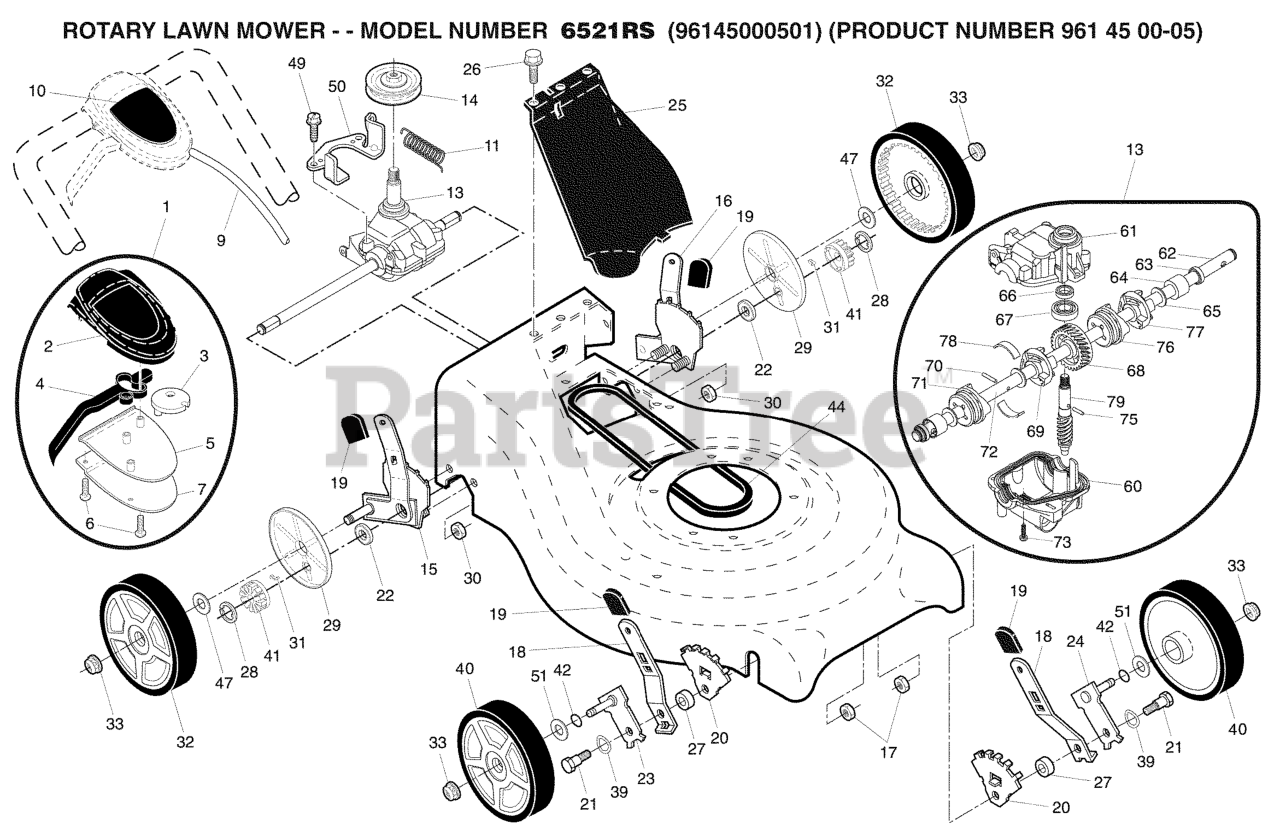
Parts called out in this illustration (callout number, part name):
1	DRIVE CONTROL ASSY, AUTO WALK
2	COVER.TOP.DRIVE.CONTROL.BLACK
3	PULLEY.CAM.DRIVE.CONTROL.EZ
4	LEVER, AUTOWALK DRIVE CONTROL
5	COVER.BOTTOM.DRIVE.CNTRL.BLACK
6	SCREW, PHILLIPS HEAD 10 X 5/8
7	BRACKET.DRIVE.CONTROL.MOUNT.BL
9	CABLE.ASSY.RGD.EZ.AUTO
10	DECAL, DRIVE
13	TRANSMISSION.21.RWGD
14	PULLEY.1.PIECE
15	KIT.ADJUSTER.ASM
16	KIT WHEEL ADJ LH
17	LOCKNUT 5/16-18
18	SELECTOR SPRING, FRONT
19	KNOB.DELUXE.GRAY
20	WHEEL ADJ BRACKET FRONT
21	SHOULDER BOLT 5/16-18
22	BEARING
23	AXLE ARM ASSY FRONT RH
24	AXLE ARM ASSY FRONT LH
25	COVER.DRIVE.21.RWGD.MO
27	SPACER.HEIGHT.ADJUSTER
28	E-RING 7/16 RE
29	COVER.DUST.WHEEL
30	LOCKNUT.NYLOC.1/4-20
31	PAWL, DRIVE
32	WHEEL.8X1.75.
33	NUT.HEX.FLANGE.3/8-16.LO(3 2)
39	WASHER.CURVED.CYLINDRICAL
40	FRONT WHEEL AND TIRE ASSY 8X2
41	PINIION.14.TOOTH.RGD
42	O-RING..070X.487.NEOPRENE
44	BELT.RGD.VS
47	WASHER FLUT
50	BELT KEEPER
51	WASHER.FLAT.1/2
60	CASE, LOWER
61	CASE UPPER
62	Shaft, Output, Long
63	SEAL.OUTPUT.SHAFT
66	SEAL INPUT SHAFT
68	GEAR 28 TEETH
69	DOG.FIXED.LH.32003
70	PIN 7 33732
71	DOG.MOVEABLE.LH.32005
72	Shaft, Output, Short
75	PIN 3.50.337 - 33733
76	DOG.FIXED.RH.32004
77	DOG.MOVEABLE.RH.32006
78	SPRING LEAF
79	SHAFT WORM
